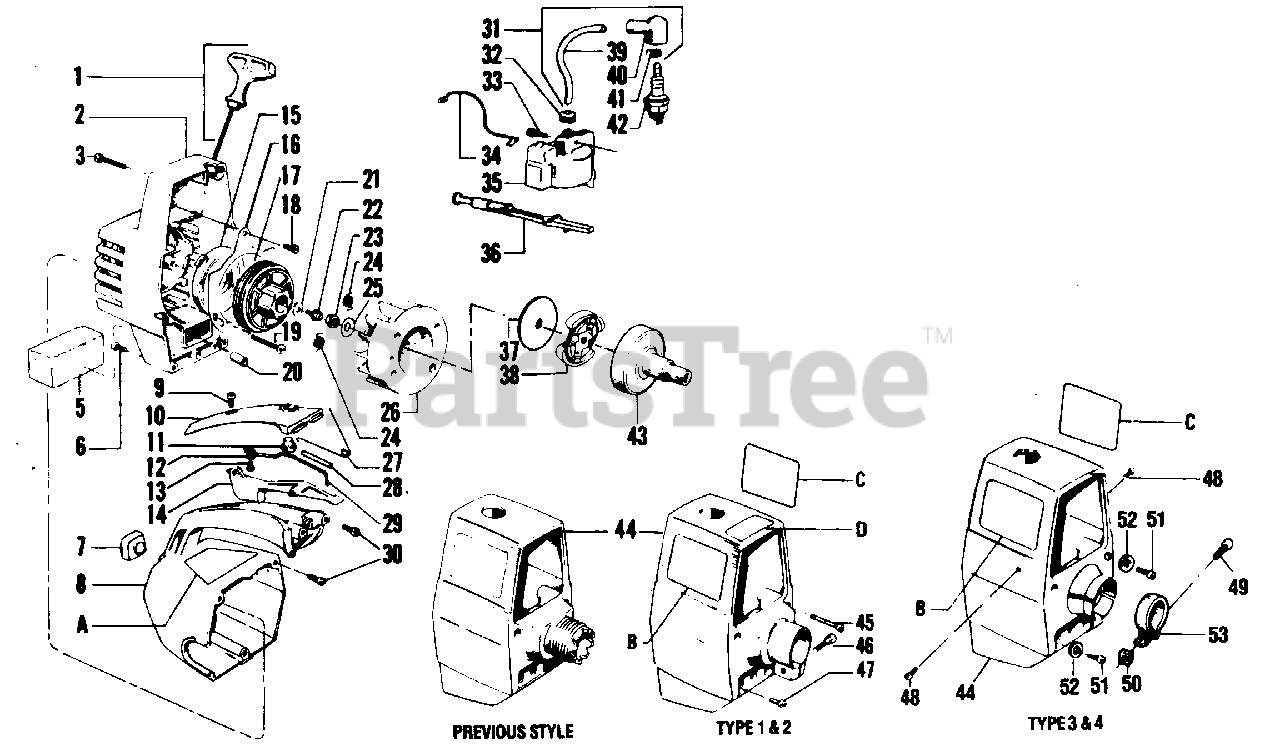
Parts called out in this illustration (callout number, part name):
2	Fan Housing (Incl. #16, 18, 19, 20 & 28) See Service Ref. 8
5	Air Filter
7	Bumper - Fuel Tank Housing
8	Handle and Fuel Tank Housing
9	Screw - 8 - 16x3/4" - Pan Hd. - Handle Cover
10	Handle Cover
11	Button - Kill Switch
12	Washer - Kill Switch
13	Screw - 8 - 16x3/8"-Pan Head -
14	Trigger - Throttle
15	Models XR-50 Type 2, 3 & 4
16	Air Baffle
17	Starter Pulley (Incl. #21), Model XR-50 Type 2, 3 & 4
21	Washer - Starter Pulley
23	Nut - Flywheel - 5/16x24" - Fil. Hd.
24	Spring - Starter Dog
25	Washer - Flywheel
26	Flywheel Assembly (Incl. #24)
27	Trigger Spring
28	Insulation - Switch Spring
29	Spring - Kill Switch
30	Screw - 10 - 14x3/4" Pan Head Fan Hsg. to Handle & Fuel Tank
31	BEVEL GEAR COMPLETE
32	Grommet - Plug Wire
33	Screw - 8 - 32x3/4-Fil. Hd. -Ignition Module
34	Lead Wire - Switch
35	Kit - Ignition Module
36	Knob - Choke
37	Kit - Clutch - Washer
38	Kit - Clutch Ass'y
39	High Tension Lead Wire
40	Boot - Spark Plug
41	Connector - Spark Plug Lead
42	Spark Plug - CJ-14
43	Coupling and Bearing Assembly
44	Previous Style
44	Type 1 & 2
44	Type 3 & 4
45	Screw - Shroud (Top) - Type 1 & 2
46	Bolt - Pinch Clamp - Type 1 & 2
47	Screw - Shroud (Bottom) - Type 1 & 2
48	Screw - Type 3 & 4
49	Bolt - Type 3 & 4
50	Nut - Type 3 & 4
51	Screw - Type 3 & 4
52	Washer - Type 3 & 4
53	Clamp - Shroud - Type 3 & 4
A	Models XR-50,XR-70 - Type 1
A	Model XR-50 Type 2
A	Model XR-50 Type 3
A	Model XR-50 Type 4
B	Model XR-50
B	Model XR-70
C	Model XR-50
C	Model XR-70
D	Decal - Shroud (Top) - Model XR-7Q
